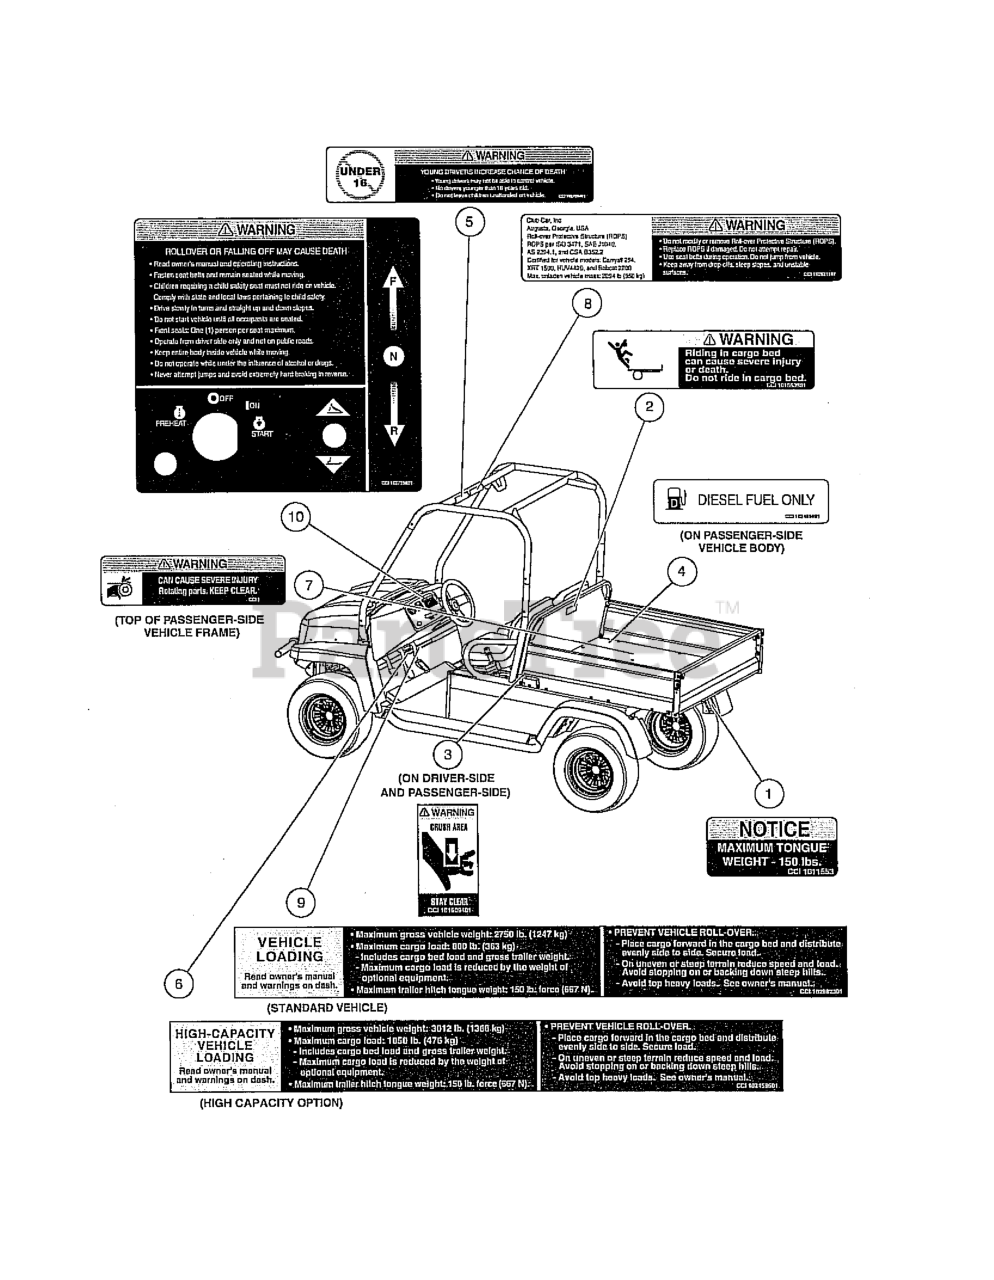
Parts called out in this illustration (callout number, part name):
1	DECAL, TRAILER HITCH
2	DECAL, BED LOAD WARNING
3	DECAL, CRUSH AREA WARNING
4	DECAL, DIESEL FUEL ONLY
5	DECAL, WARNING UNDER 16
6	DECAL, VEH LOAD HIGH CAPACITY
7	DECAL, WARNING ROTATING PARTS
8	DECAL, WARNING-CERTIFIED ROPS
9	DECAL, VEHICLE LOAD, 2750 LBS
10	DECAL-WARNING
